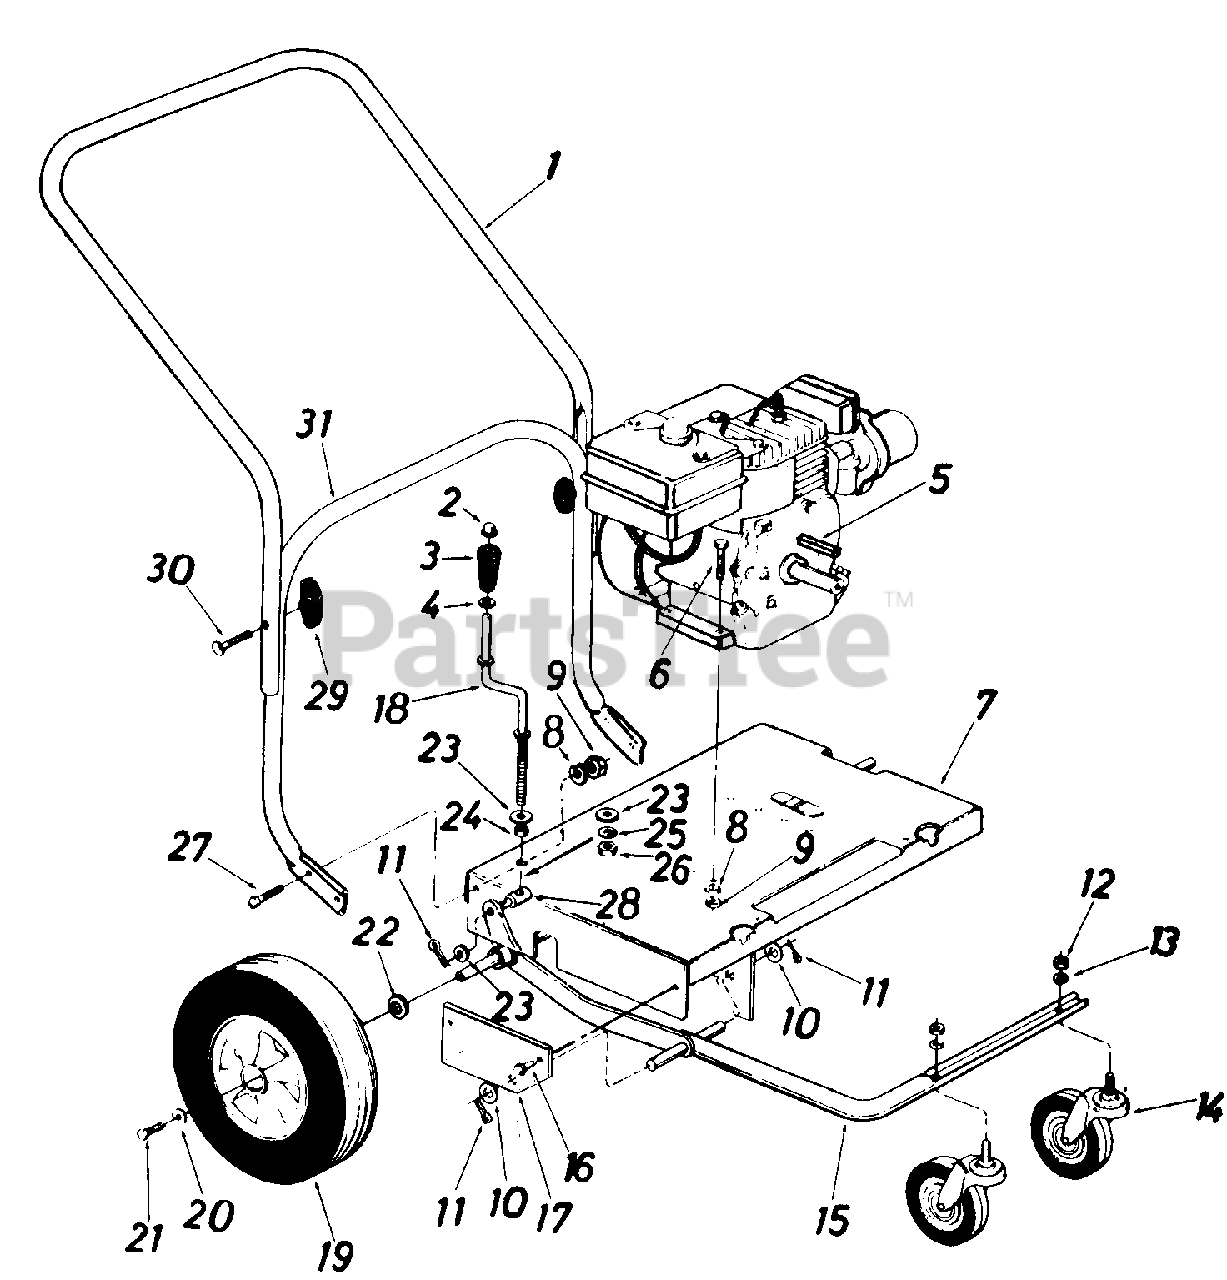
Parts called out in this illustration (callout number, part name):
1	Upper Handle
2	Push Nut 3/8" Rod
3	Crank Knob
4	Fl.-Wash. .385" I.D. x .62" O.D.
5	Sq. Key 1/4" x 2.0" Lg.*
6	Hex Bolt 5/16-18 x 1.50" Lg.*
7	Engine Mounting Fram Ass'y.
8	L.-Wash. 5/16" I.D.*
9	Hex Nut 5/16-18 Thd.*
10	Fl.-Wash. .63" I.D. x 1.25" O.D.
11	Cotter Pin 1/8" Dia. x 1.0" Lg.
12	Hex Nut 1/2-13 Thd.*
13	L.-Wash . 1/2 " I . D.*
14	Swivel Caster Wheel 5 " Dia. x 1.25"
19	Wheel Ass y. Comp. 12" x 3" (Plastic)(Incl. Bearings)
20	Fl.-Wash.34" I.D. x.87" O.D.
21	Hex Locking Bolt 5/16-24 x.62" Lg.
22	Fl.-Wash.
23	Fl.-Wash. .38" I.D. x .57" O.D.
24	Spacer .382" I.D. x .50" O.D. x .180" Lg.
25	L.-Wash. 3/8" I.D.*
26	Hex Nut 3/8-16 Thd.4
27	Hex BoIt 5/16-18x .75" Lg.*
28	Ferrule
29	Hand Knob
30	Carriage Bolt 5/16-18 x 2.0" Lg.
31	Lower Handle
